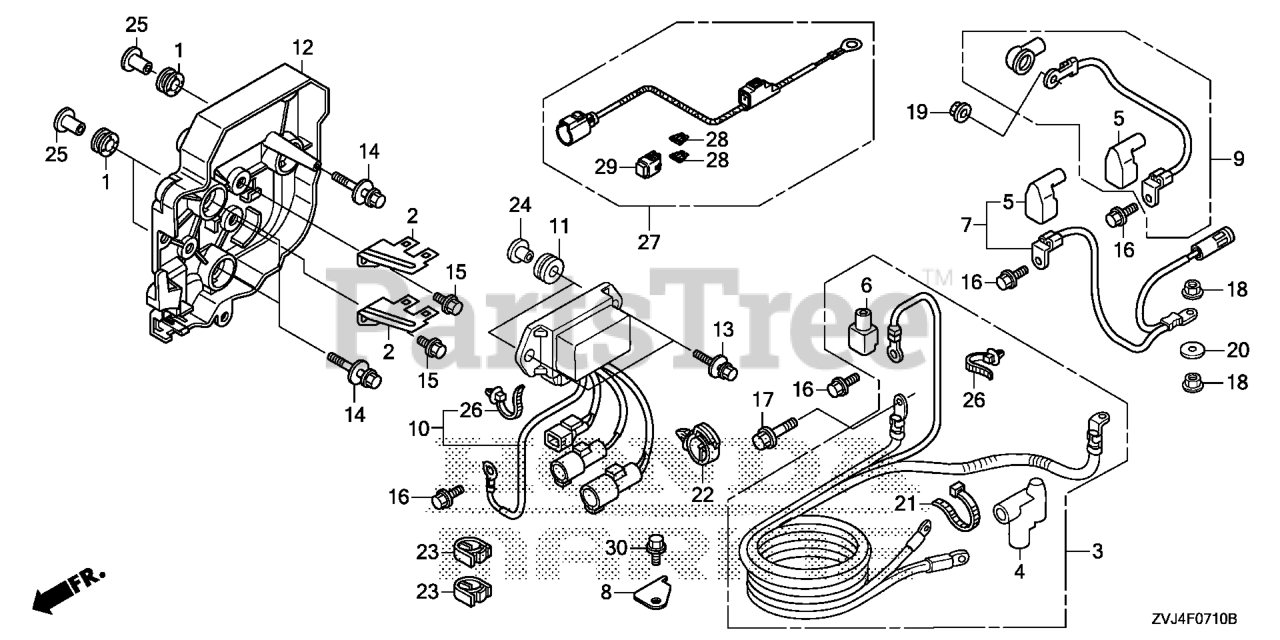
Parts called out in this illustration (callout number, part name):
1	GROMMET, ELECTRONIC PARTS CASE
2	BRACKET, CONNECTOR C
3	CABLE ASSY., STARTER
4	COVER, STARTER TERMINAL
5	COVER B, TERMINAL (L)
6	COVER B, TERMINAL
7	CABLE ASSY., POWER TILT RELAY
8	PLATE, STARTER CABLE
9	WIRE, ALTERNATOR
10	RELAY ASSY., POWER TILT
11	GROMMET, RELAY
12	CASE, POWER TILT RELAY
13	BOLT-WASHER (6X25)
14	BOLT-WASHER (6X27)
15	BOLT, FLANGE (6X10)
16	BOLT, FLANGE (6X12)
17	BOLT, FLANGE (8X18)
18	NUT-WASHER (8MM)
19	NUT-WASHER (6MM)
20	WASHER, PLAIN (8MM)
21	BAND, WIRE (165MM) (BLACK)
22	CLIP, WIRE HARNESS
23	CLIP, WIRE HARNESS
24	COLLAR, MOUNTING (6MM)
25	COLLAR, MODULE IGNITION CONTROL CASE (CDI)
26	CLIP, HARNESS BAND (145MM) (BLACK)
27	HARNESS ASSY., POWER
28	FUSE, BLADE (40A)
29	COVER ASSY., FUSE (40A)
30	BOLT, FLANGE (6X12) Use from Frame SN 1005249.
